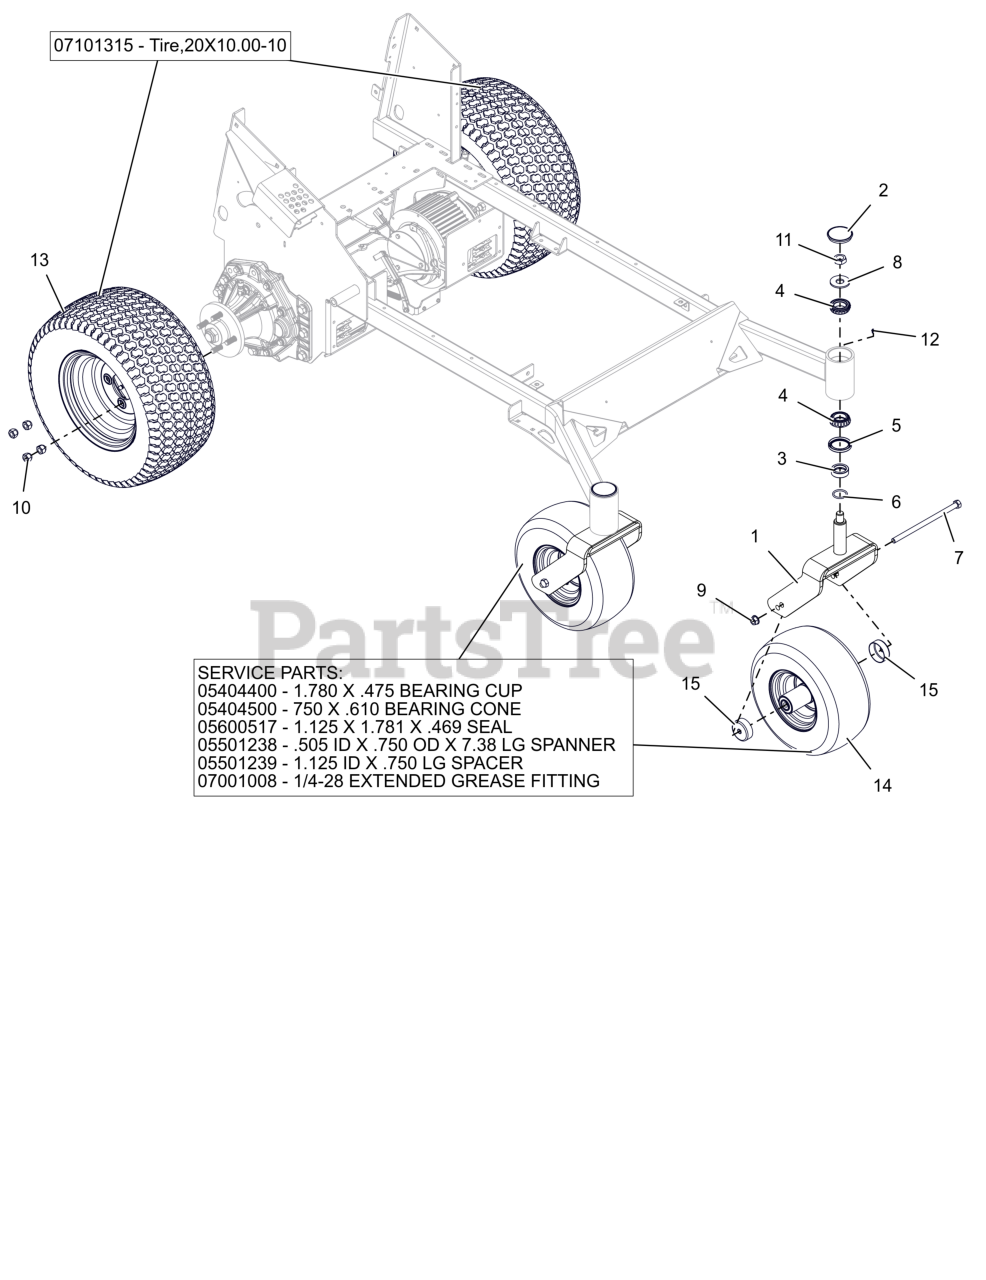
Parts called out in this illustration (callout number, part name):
1	CASTER FORK WMT - RED
2	CAP, DUST
3	SPCR, FRONT CASTER FORK
4	BRG-CONE 1.25X.66
5	SEAL, OIL 1.75 X 2.332 X .312
7	BLT, HEX .50-13X9.00 G5 ZCC
8	WSHR-FL-STL 0.812X2X0.148 ZCC
9	NUT-LK-TOP-FLG .500-13 GF ZCC
10	NUT, WHEEL .50-20 ZCC
11	NUT, JAM-TOPLOCK .750-16 ZCC
12	FTG, .25-28 FLUSH MNT GREASE
13	ASM- WHL/TIRE 20X10-10
13	TIRE, 20X10.00-10 (MONITOR)
13	TIRE, 20X10.00-10
14	ASSM TIRE\WHEEL 13X6.50-6 SEMI LOW GLOSS BLACK
14	BRG-CUP 1.781X.475
14	BRG-CONE .750X.61
14	SEAL, 1.125 X 1.781 X .469
14	SPANNER,.505ID X.750OD X7.38LG
14	SPACER, 1.125 ID X .750 LG
14	GREASE FITTING 1/4-28 EXTENDED
15	SHIELD, WHEEL BEARING
